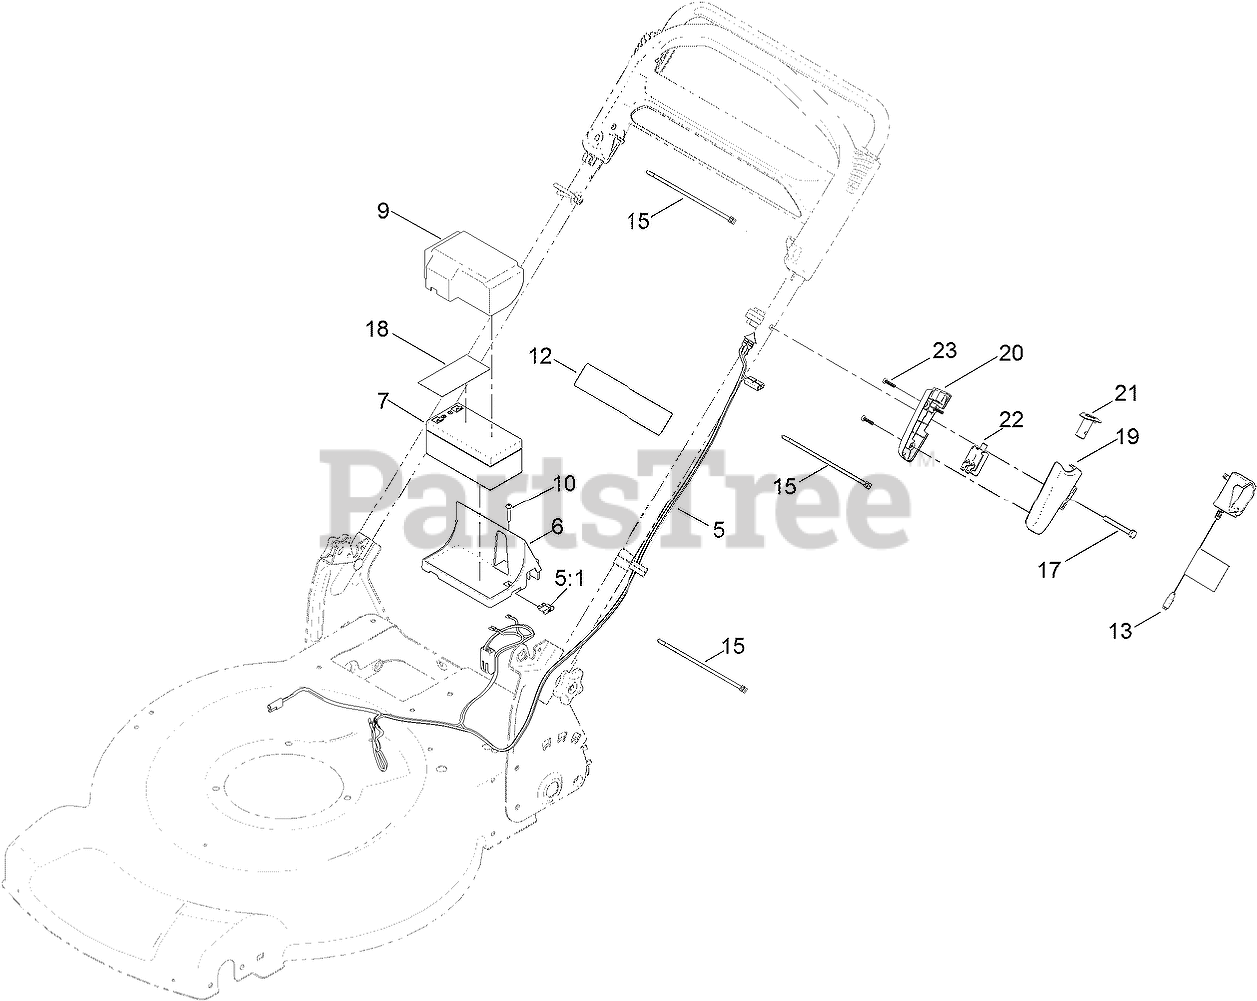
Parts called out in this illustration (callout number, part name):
5	HARNESS-WIRE
5:1	FUSE-40 AMP
6	TRAY-BATTERY
7	BATTERY-WET
9	COVER-BATTERY
10	SCREW-PPH, PLASTITE
12	DECAL-WARNING
13	CHARGER-BATTERY
15	TIE-CABLE
17	SCREW-HH
18	DECAL-TERMINAL, BATTERY
19	HOUSING-SWITCH, LH
20	HOUSING-SWITCH, RH
21	BUTTON-SWITCH
22	SWITCH-PUSH BUTTON
23	SCREW-PPH
